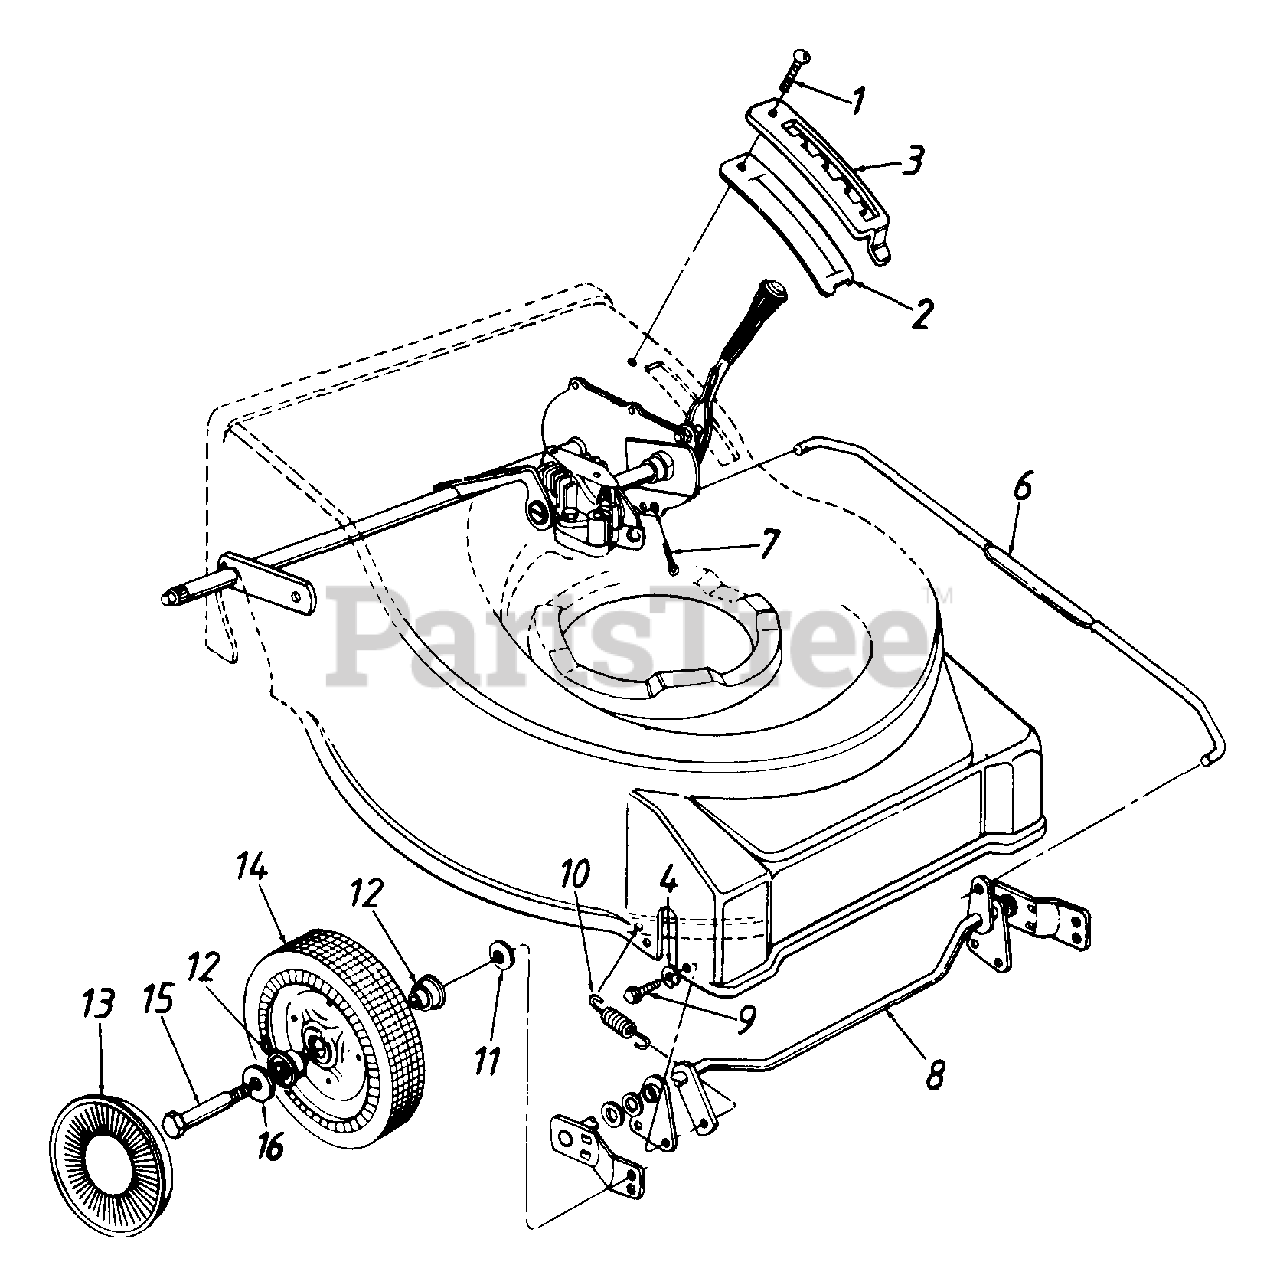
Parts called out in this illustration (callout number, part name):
1	Torx Mach. AB-Tap Scr. 1/4 x .62" Lg.
2	Height Adjustment Support
3	Height Adjustment Plate
4	L-Wash. 1/4" I.D.
6	Height Adj. Connecting Rod
7	Cotter Pin 3/32" Dia.
9	Hex L-Wash. Hd. AB-Tap Scr. 1/4 x .38" Lg.
10	Extension Spring 2.39" Lg.
11	Bell-Wash..380" I.D. x .88"
12	Flange Ball Bearing 1/2" I.D.
13	Hub Cap (See Below)
14	Wheel Ass'y. Comp.- Front
15	Shld. Bolt .498" Dia. x 1.45"
16	Wave Wash..53" I.D. x .78"
